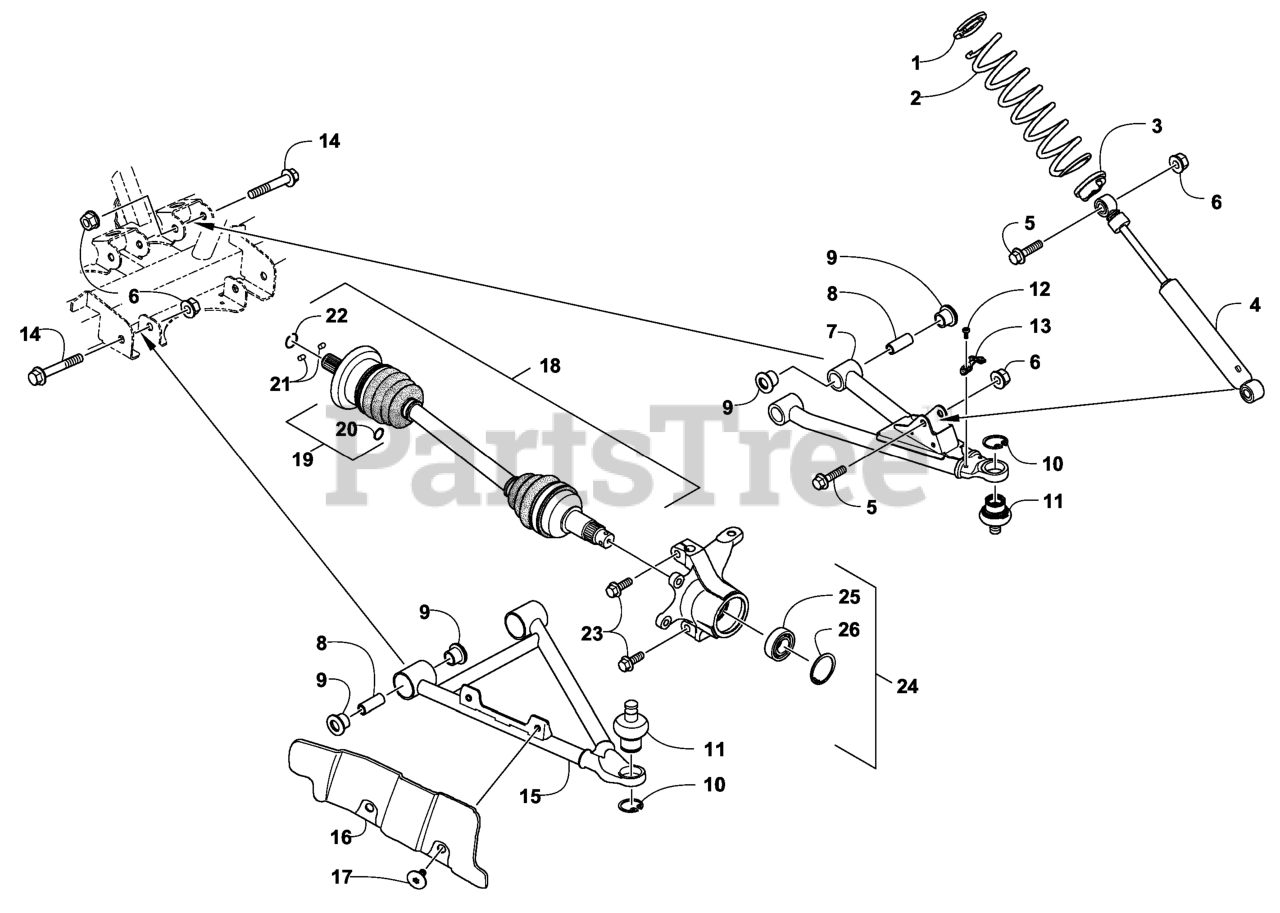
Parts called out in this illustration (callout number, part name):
1	RETAINER-SPRING
2	SPRING-COIL
3	ADJUSTER-CAM, SPRING
4	SHOCK ABSORBER
7	A-ARM, FRONT UPPER (LH AS
8	COLLAR-SUSPENSION BUSHING
9	BUSHING-SUSPENSION, A-ARM
10	CLIP-BALL JOINT
11	BALLJOINT ASM (DOUBLE STA
12	SCREW-TSPNH, SELFTAP
13	CLIP-BRAKE HOSE
14	SCREW-HFH
15	A-ARM, FRONT LOWER (LH AS
16	GUARD-BOOT, RH
16	GUARD-BOOT, LH
17	SCREW-SELF TAP
18	KIT-HALFSHAFT
19	KIT-CV BOOT, UNIVERSAL
20	CIRCLI-HALFSHAFT, INTERNA
21	PIN-TRANSFER, SHORT
22	CIRCLIP
23	SCREW-SHLDR
24	KNUCKLE-STEERING, RH ASM
25	BEARING-WHEEL
26	RING-RETAINING
